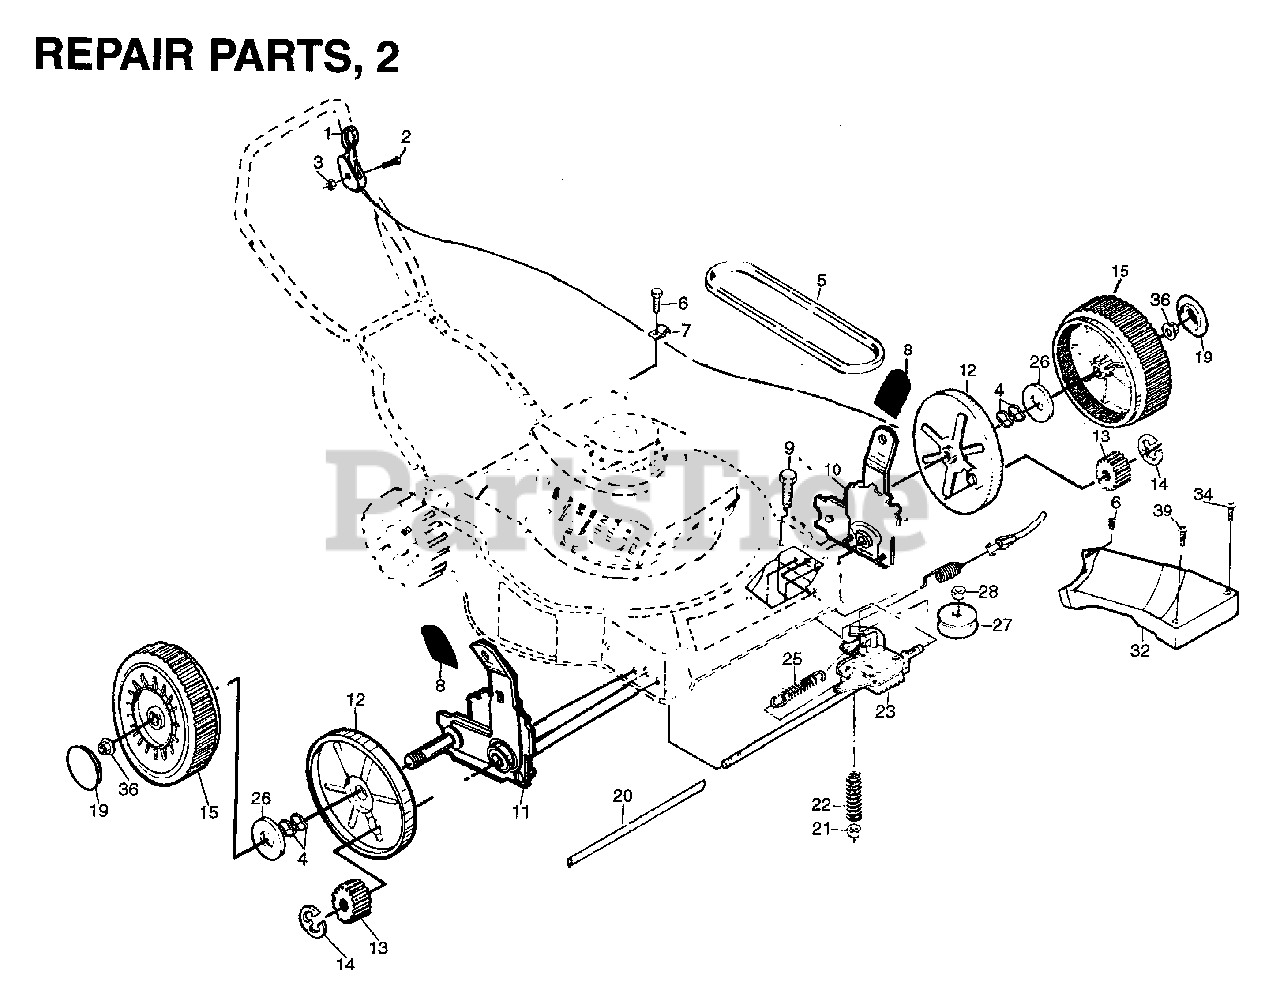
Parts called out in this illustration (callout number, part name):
1	CONTROL
2	SCREW 1/4-20 X 2.12
3	NUT.CROWNLOCK.1/4
4	WAVE WASHER
5	BELT DRIVE
7	GUIDE CLIP PM
8	SELECTOR KNOB
12	DUST SHROUD PM
13	PINION GEAR
14	E-RING 7/16 RE
15	WHEEL & TIRE 8 X 2
20	DRV SHAFT TUBE PM
21	NUT.CROWNLOCK.1/4
22	SPRING.EXTENSION
23	GEAR CASE ASMBLY
26	WASHER FLUT
27	PULLEY
28	FLANGED LOCKNUT 3/8-16 ZINC
36	HEX FLANGE LOCKNT
39	SCREW.SLOT.TORX.
